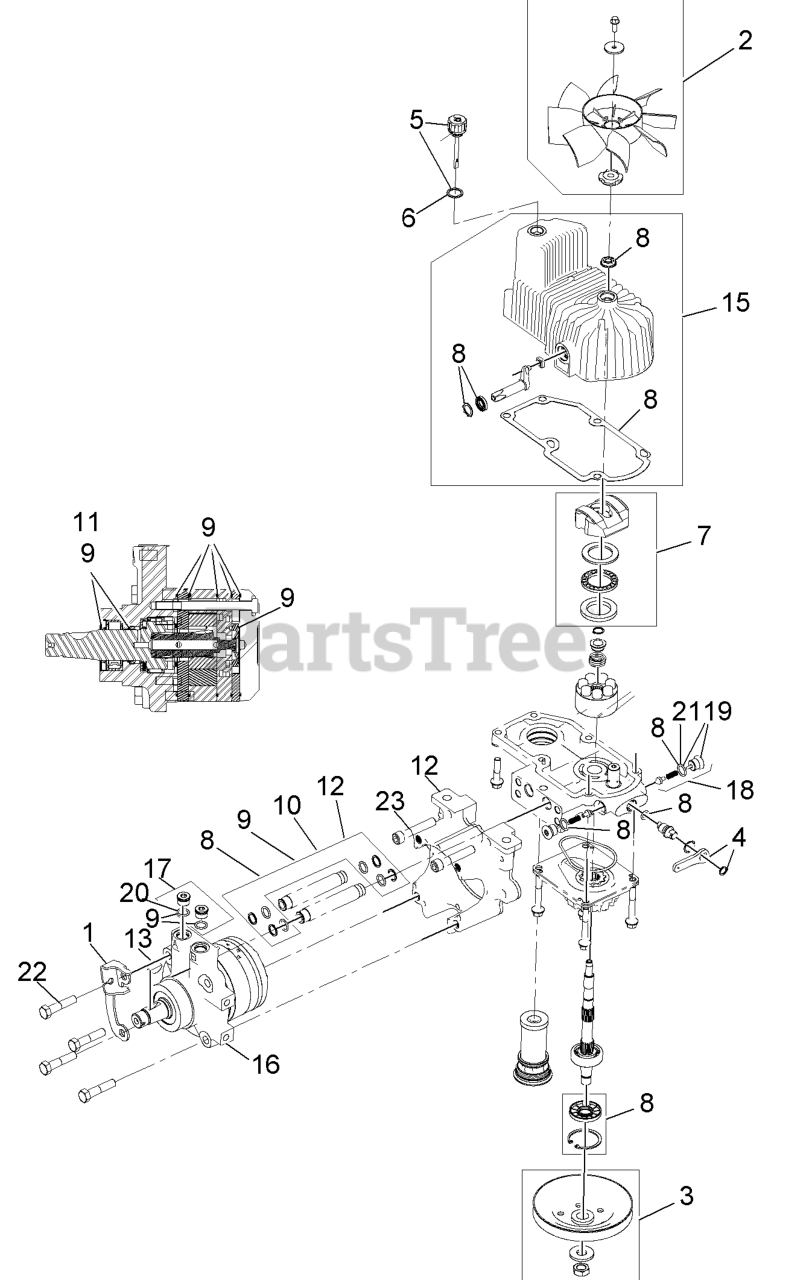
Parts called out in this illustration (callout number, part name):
1	BRACKET-ANCHOR, CABLE
2	FAN KIT
3	PULLEY KIT
4	HANDLE-BYPASS VALVE, HYDRO
5	DIPSTICK-HYDRO W/GASKET
6	GASKET-DIPSTICK, HYDRO
7	SWASH BLOCK KIT
8	PUMP SEAL KIT
9	MOTOR SEAL KIT
10	TUBE SEAL KIT
11	OUTPUT SHAFT SEAL KIT
12	NOSE CUP-UHT
13	KEY-WOODRUFF
15	HOUSING-HYDRO, LH
16	MOTOR-HYDRAULIC LH 240CC
17	MAGNETIC PLUGS SERVICE KIT
18	CHECK VALVE ASM
19	PLUG-CHECK (W/O-RING)
21	O-RING-CHECK VALVE
22	SCREW HH
23	SCREW-HSH
